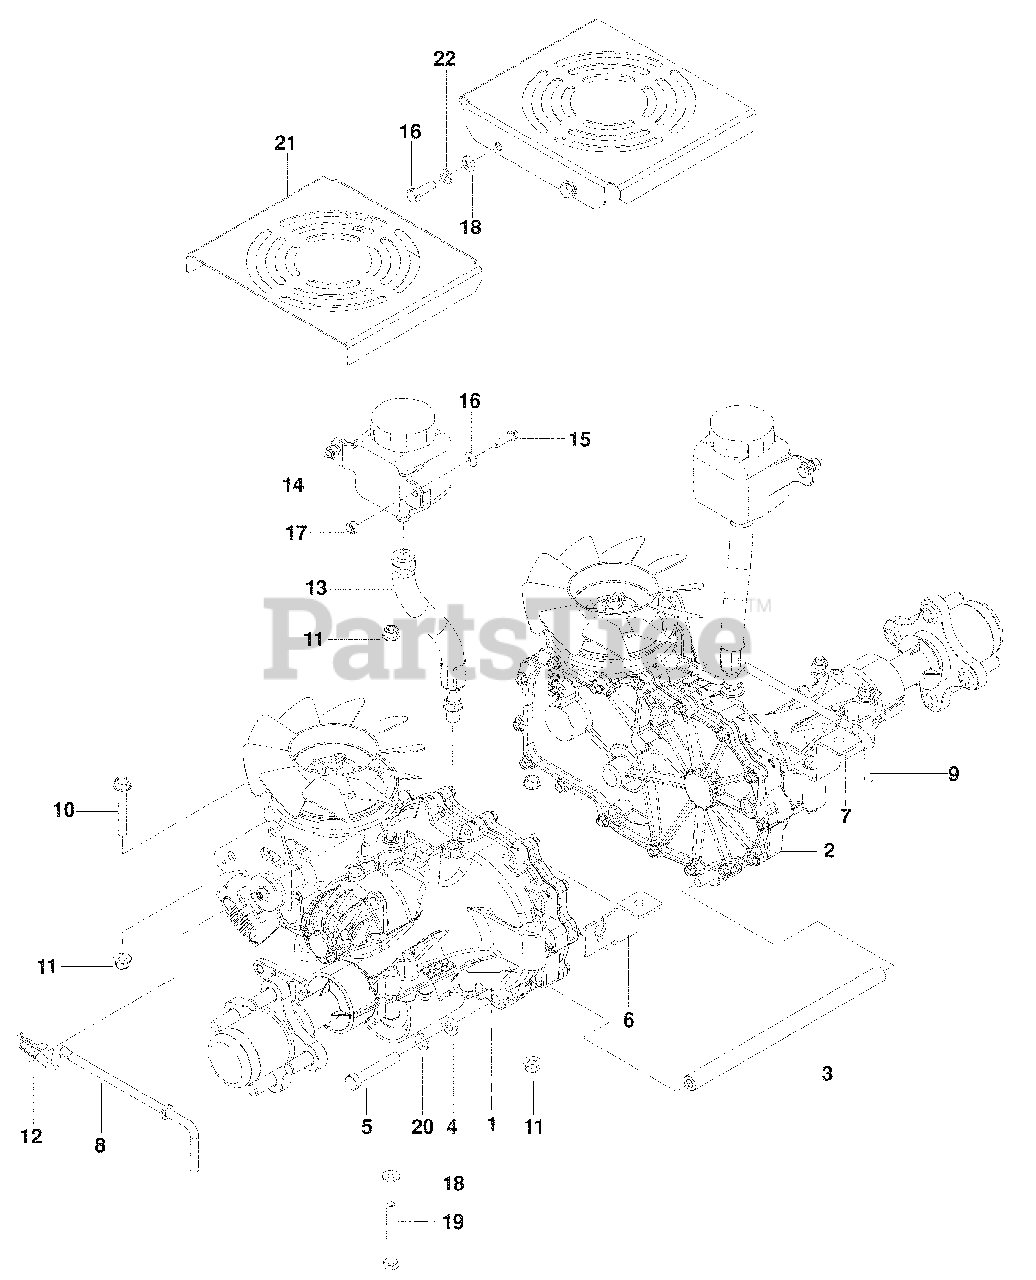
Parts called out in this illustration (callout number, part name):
1	TRANS, ZT-3400, LT
2	TRANS, ZT-3400, RT
3	TUBE, SPACER, 3400
4	WASHER, 3/8 SAE FLT
5	HCS 3/8-16 x 2½ GR8
6	BRACKET, TRANS, LT
7	BRACKET, TRANS, RT
8	LINKAGE, LEFT BYPASS
9	LINKAGE, RIGHT BYPASS
10	HHFS 5/16-18 x 2¼
11	NUT 5/16-18 HEX FLG NYLOC
12	HAIRPIN COTTER
13	HOSE, EXPANSION
14	TANK, EXPANSION
15	HCS ¼-20 x 7/8
16	WASHER ¼ FLAT SAE
17	NUT ¼-20 HEX NYLOC
18	WASHER 5/16 SAE FLAT
19	HCS 5/16-18 x 2¾
20	WASHER 3/8 SPLT LK
21	COVER, FAN
22	WASHER 5/16 SLW
